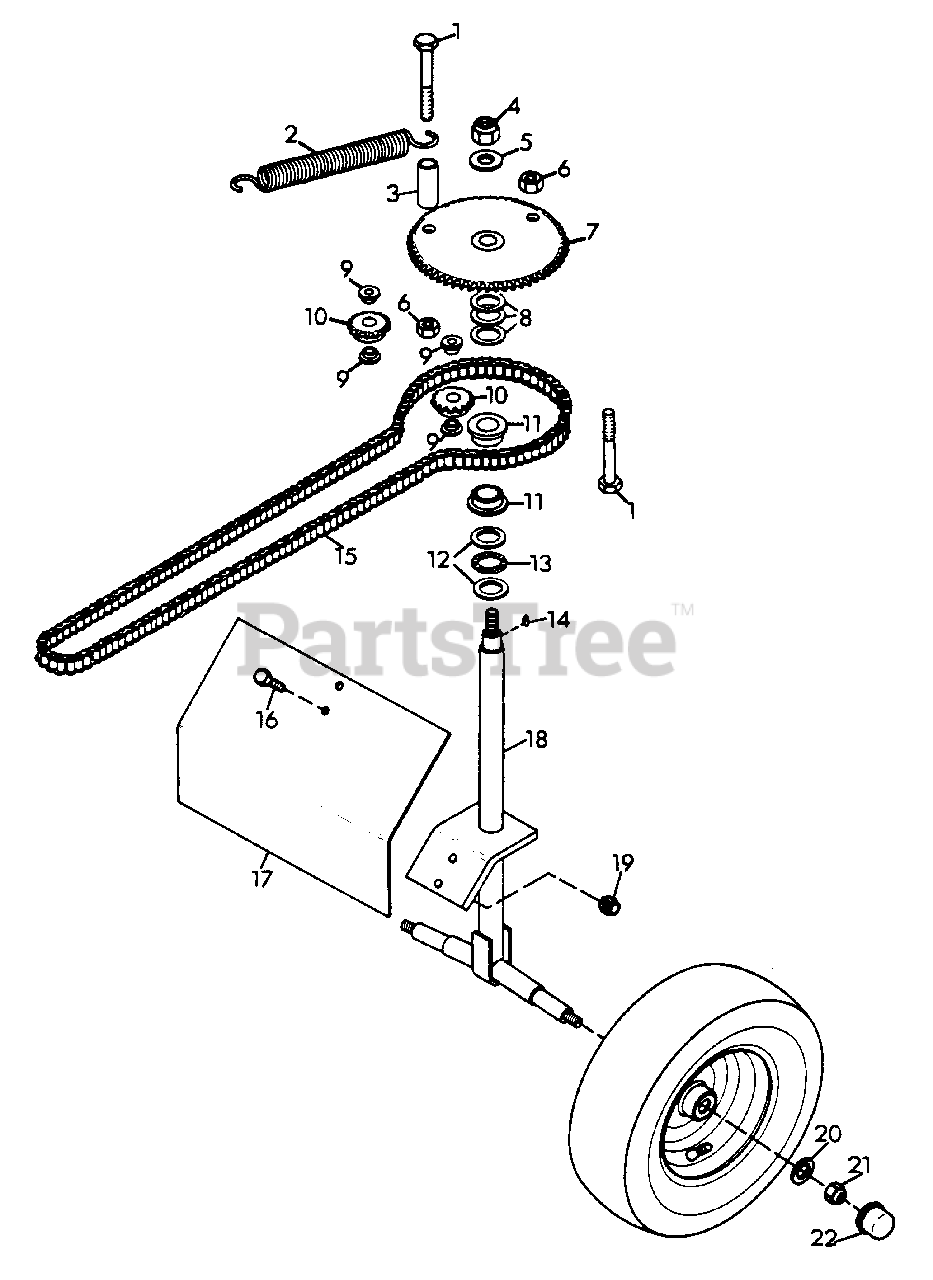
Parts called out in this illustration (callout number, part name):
1	BOLT, HEX 1/2-13X3.25
2	SPRING
3	SPACER, .850X.546X2.18
4	NUT, LOCK 7/8-9
5	WASHER, FLAT .969X2.250X.165
6	NUT, HEX 1/2-13
7	WELDMENT, SPROCKET #40
8	RACE, THRUST
9	BUSHING
10	SPROCKET, DRIVE
11	BEARING, FLANGED
12	BEARING, THRUST RACE
13	BEARING, NEEDLE THRUST
14	KEY, WOODRUFF .250X.875 HARD #A
15	CHAIN, #40
16	BOLT, HEX 1/2-13X1.25
17	FENDER, PRO MASTER
18	WELDMENT, PRO MASTER AXLE
19	NUT, LOCK 1/2-13
20	WASHER, FLAT .812X1.496X.134
21	NUT, LOCK 3/4-10
22	CAP, DUST
